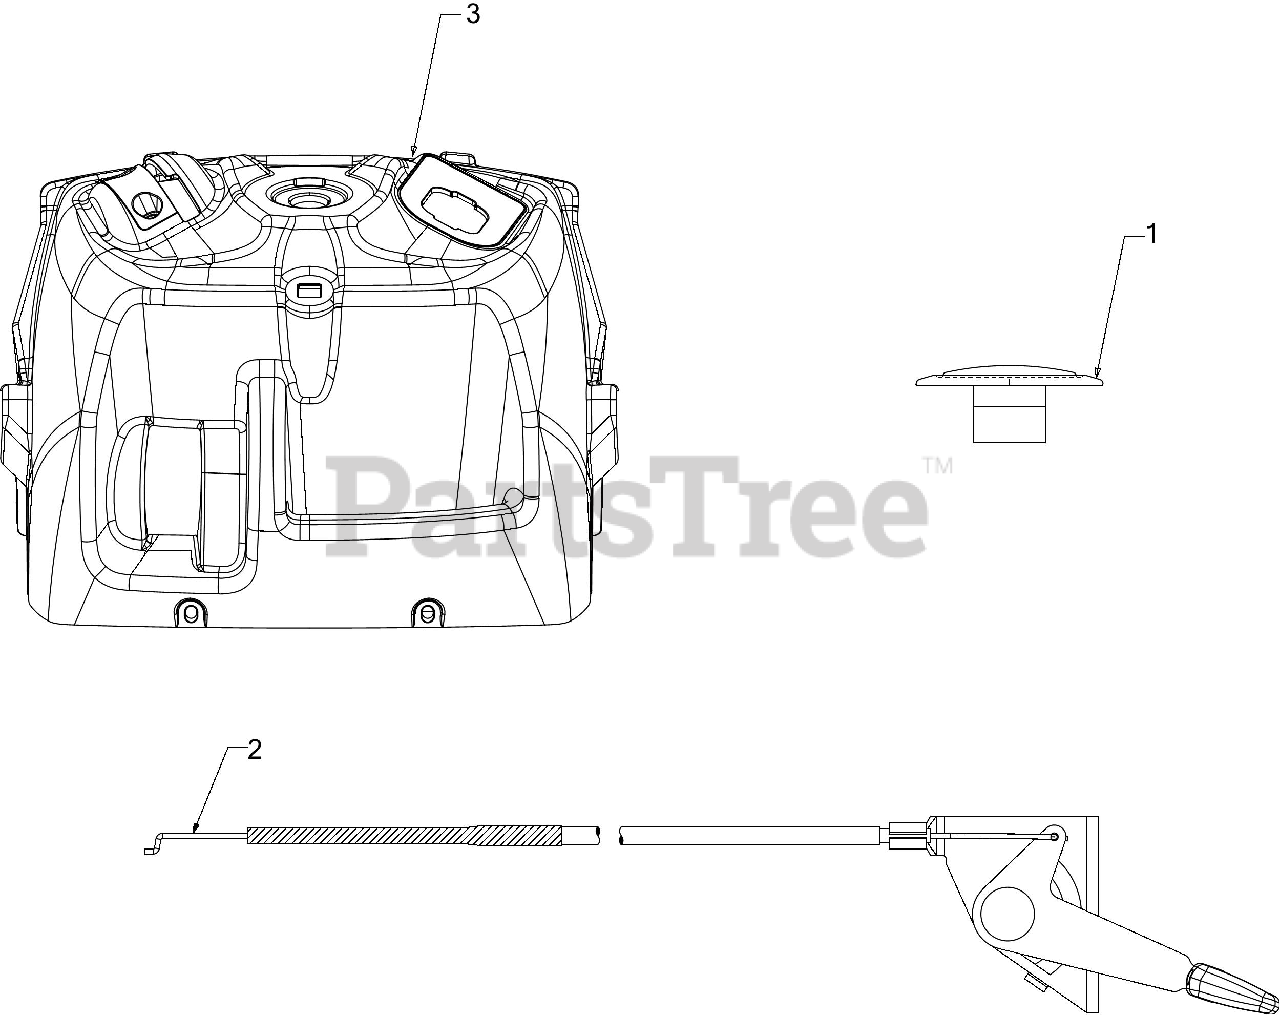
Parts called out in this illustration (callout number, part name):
1	CHOKE PLUG
2	THROTTLE CABLE 28" x 1.1
3	UPPER DASH
